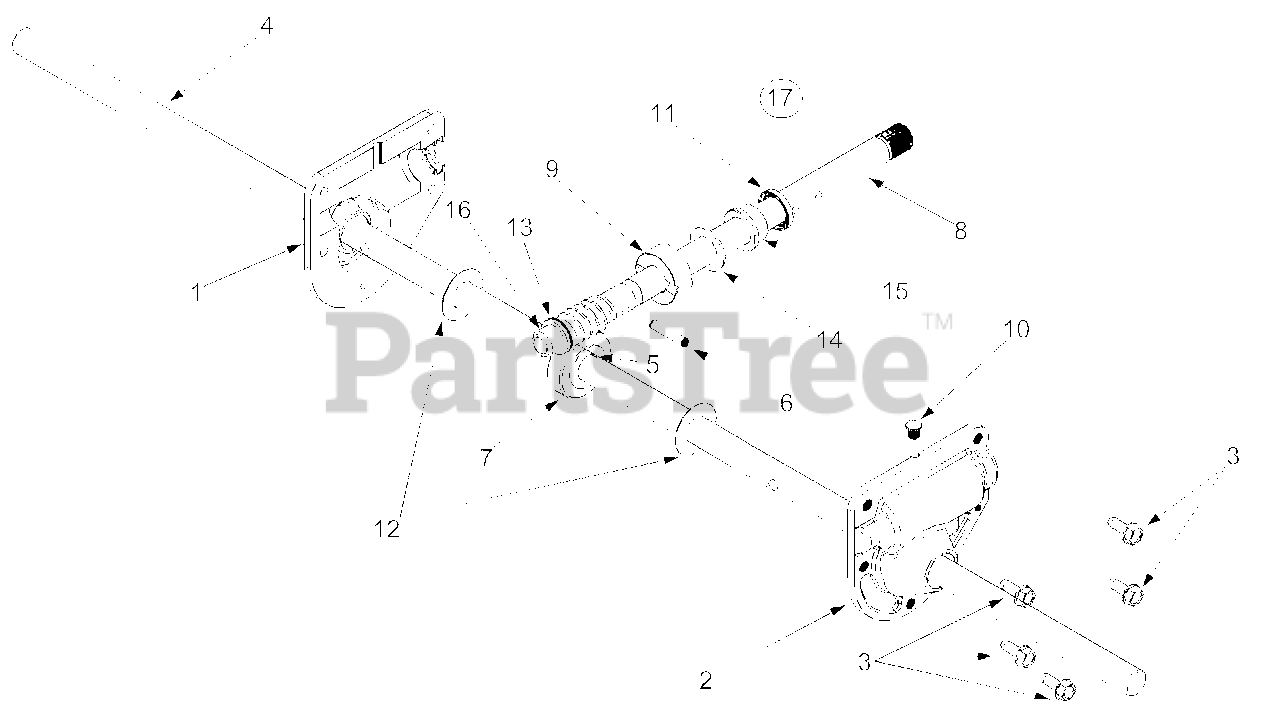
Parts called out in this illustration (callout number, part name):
1	RH Housing
2	LH Housing
3	Self Tapping Screw, 1/4-20 x .75
4	Spiral Axle 26"
5	Hi-Pro Key, 3/16 x 5/8
6	Spring Spiral Pin, .25 x 1.25
7	Worm Gear, 20-tooth
8	Worm Shaft
9	Thrust Collar
10	Grease Plug
11	Grease Seal
12	Flat Washer, .76 x 1.5 x .030
13	Flat Washer, .508 x 1.0 x .020
14	Flat Washer, .76 x 1.5 x .060
15	Flange Bearing, .75 x 1.0 x .59
16	Flange Bearing, .503 ID x .75 OD
17	Gear Assembly Complete, 26"
